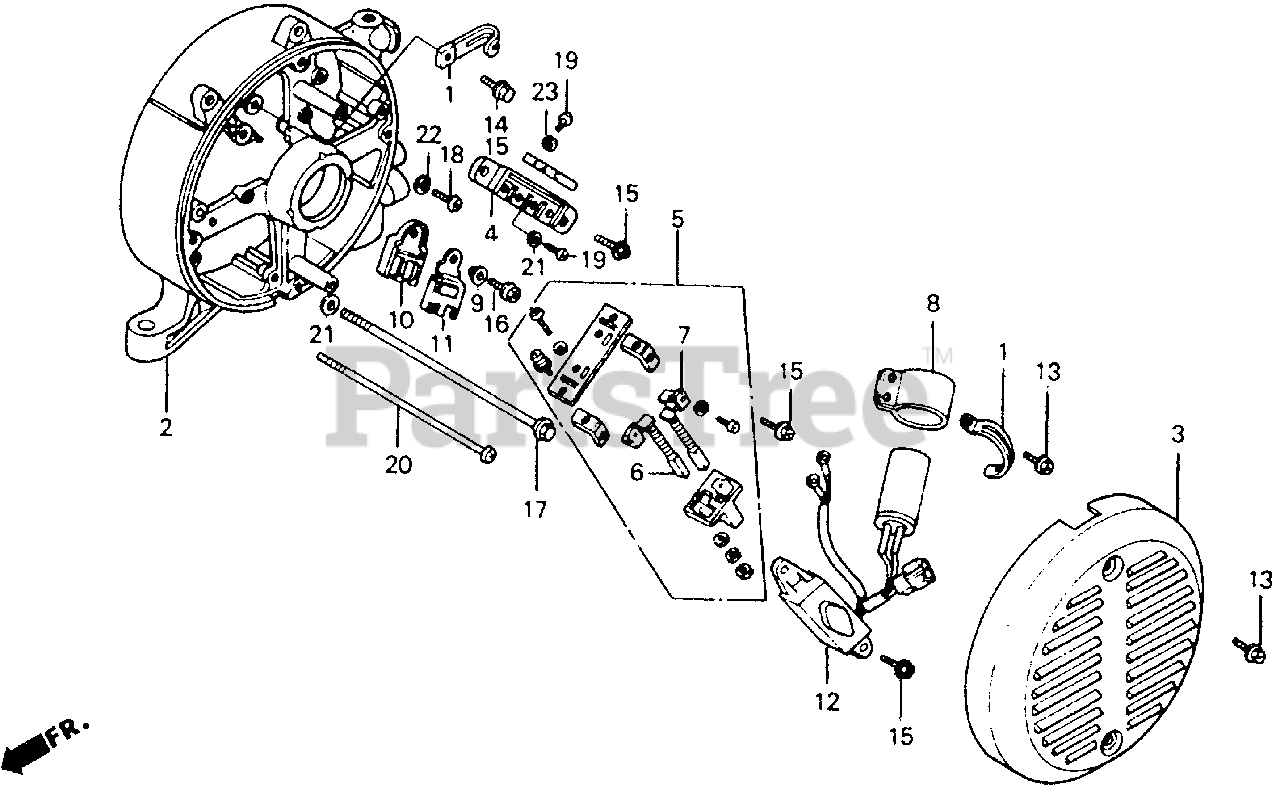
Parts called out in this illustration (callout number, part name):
1	CLAMP B, WIRE
2	HOUSING, RR. *R8* (BRIGHT RED) (NOT AVAILABLE)
3	COVER, ALTERNATOR END *R8* (BRIGHT RED) (NOT AVAILABLE)
4	TERMINAL, A.C. OUT
5	HOLDER ASSY., BRUSH
8	HOLDER, CONDENSER
9	BUSH, INSULATING
10	INSULATOR, DIODE
11	DIODE, D.C.
12	REGULATOR ASSY., AUTOMATIC VOLTAGE
13	SCREW, TAPPING (5X12)
14	SCREW, TAPPING (5X14)
15	SCREW, TAPPING (5X14)
16	SCREW, TAPPING (5X16)
17	BOLT, HEX. (6X202)
18	SCREW, PAN (5X12)
19	SCREW, PAN (6X8)
20	SCREW-WASHER (5X160)
21	WASHER, PLAIN (6MM)
22	WASHER, SPRING (5MM)
23	WASHER, SPRING (6MM)
